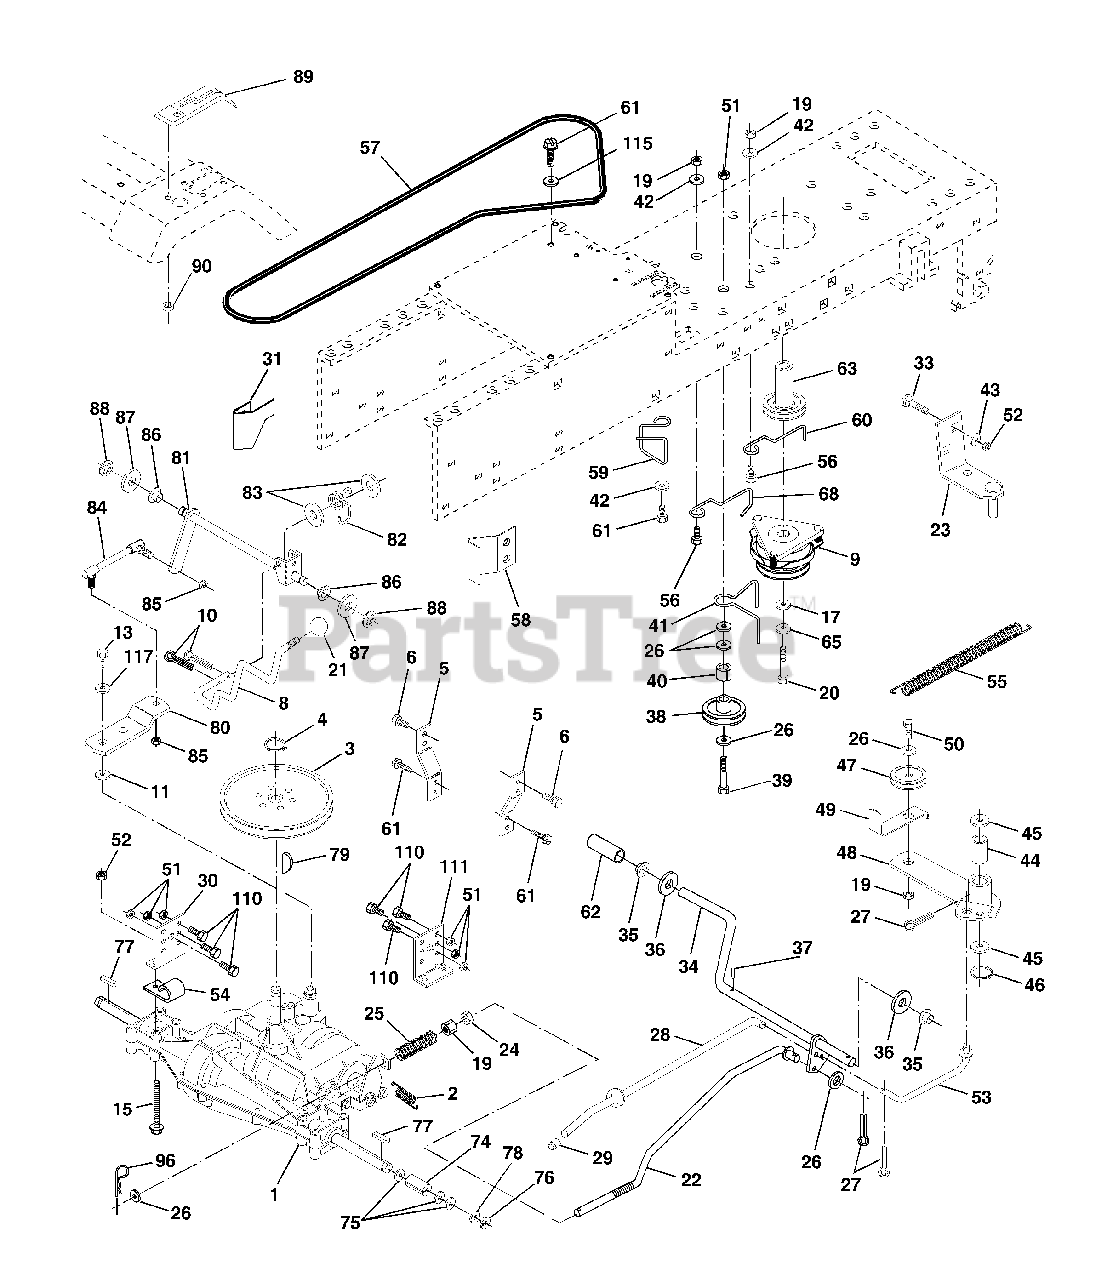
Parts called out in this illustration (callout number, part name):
2	Spring Extension Brake
3	Pulley Transaxle 18" tires
4	Ring Retainer # 5100-62
5	Strap Torque Rh Pnt Blk
6	Screw 5/16-18 X 3/4
7	Bracket T/A Saddle Shift
8	Rod Shifter Black(dana)
10	Pin
11	Washer Plate Shf 388 Sq Hole
12	Washer 15/32 X 3/4 X 16ga
13	Bolt 1/4-28 UNF Gr. 8 W/Patch
14	Washer
18	Bolt Fin Hex 3/8-16 UNC x 1 Gr. 5
19	Nut
21	Knob Rd 1/2-13 Plstc Thds Blk
22	Rod Brake Lt
24	Nut
25	Spring Rod Brake 2 00 Zinc
26	Washer
27	Pin
28	Rod Brake Parking Lt/Yt
29	Cap Parking Brake
30	Bracket Transmission
32	Bolt
34	Shaft Asm Pedal Foot
35	Bearing Nylon Blk 629 Id
36	Washer
37	Roll Pin
38	Pulley Idler Flat
39	Bolt Fin Hex 3/8-16 Unc x 2-3/4
40	Spacer Split 395 X 59 Bzp
41	Keeper Belt Idler
42	Washer 13/32 X 13/16 X 12 Ga
47	Pulley Idler V Groove Plastic
48	Bellcrank Clutch
49	Retainer Belt Style Spring
50	Bolt
51	Nut
52	Nut
53	Link Clutch 7 66
55	Spring Return Clutch 6 75
56	Bolt
57	V-belt Ground Drive 95
59	Keeper Belt Chassis Span Ctr.
61	Screw 3/8-16x3/4
62	Cover Pedal Blk Round
63	Pulley Engine
64	Bolt, Hex 7/16-20 x 4 Grade 5
65	Washer, Lock, Hvy Hlcl Spring 7/16
66	Keeper Belt Engine Flproof
70	Guide Belt Dr Mower Rh
72	Washer 13/32 X 1-1/4 X 12 Ga
74	Spacer Axle
75	Washer 25/32 X 1 1/4 X 16 Ga
76	E Ring
77	Key Square 2 0 X 1845/ 1865
78	Washer 25/32 X 1 5/8 X 16ga
79	Key Woodruff
96	Retainer Spring 1"
112	Washer 9/32 X 3/4 X 10 Ga
113	Strap Torque Lh
116	Bolt, Rdhd Sqnk 3/8-16 x 1.25
145	Bolt Hex Flghd 5/16-18 x Gr. 5
150	Bushing Bellcrank
151	Washer 13/32 x 2 x 10 Ga.
170	Keeper Belt
202	Bolt Carr. Sh. 3/8-16 x 1-1/2 Gr. 5
204	Screw 5/16-18 x 1
